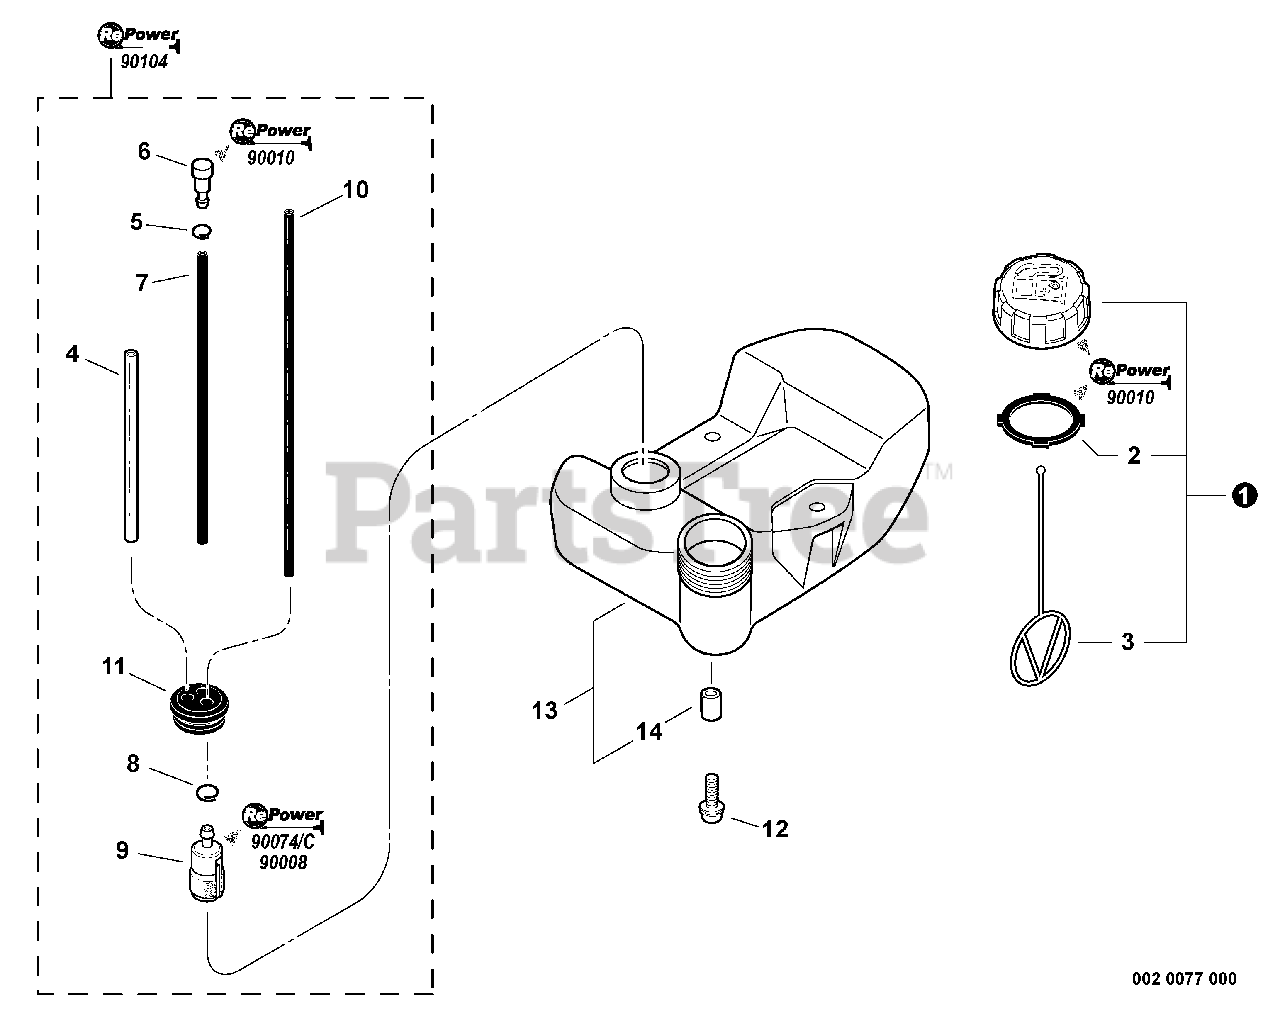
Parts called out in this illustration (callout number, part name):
1	CAP ASSY, FUEL
2	GASKET, FUEL CAP
3	CONNECTOR, CAP L= 100 MM
4	PIPE, FUEL 3×6×80 CLEAR
5	CLIP Ø6.5 MM
6	VENT ASSY
7	PIPE 3×6×115 BLACK
8	CLIP Ø6.5 MM
9	FILTER, FUEL
10	PIPE, FUEL 3×6×170
11	GROMMET, FUEL
12	SCREW 5×16
13	TANK ASSY, FUEL
14	SPACER 6.2×7.8×6
15	FUEL SYSTEM KIT
16	TUNE-UP KIT - REPOWER
17	FILTER KIT - REPOWER
18	CAP/VENT KIT - REPOWER
